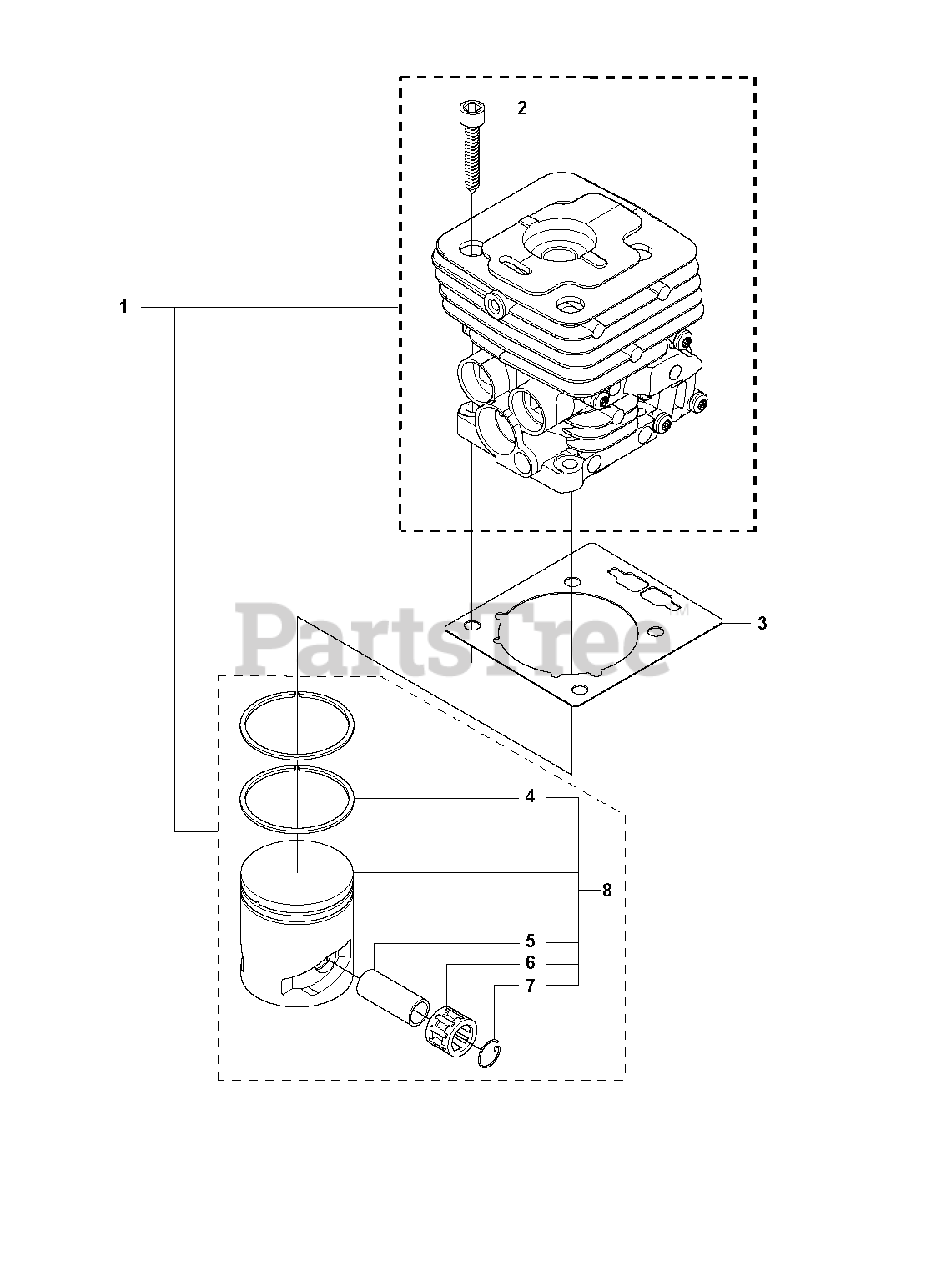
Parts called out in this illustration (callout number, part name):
1	%CYLINDER CPL
2	SCREW
3	GASKET CYLINDER
4	PISTON RING
5	PISTON BOLT
6	SUPPORT BUSHING
7	LOCKING RING
8	PISTON CPL
